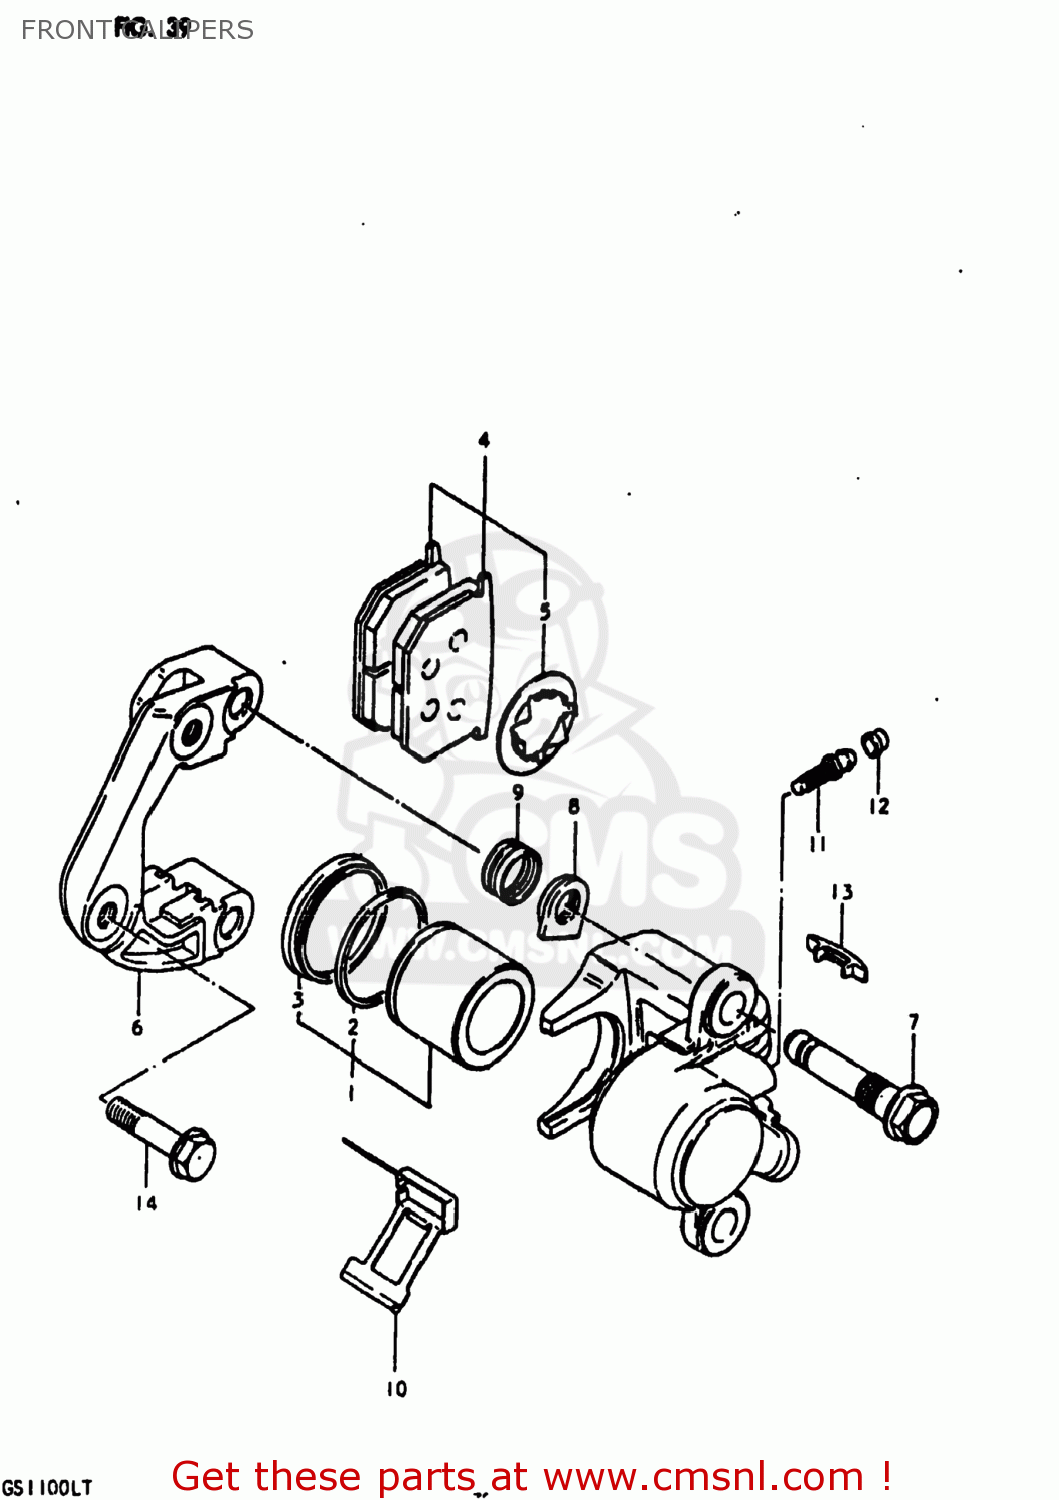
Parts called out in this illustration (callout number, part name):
0	CALIPERS ASSY.L
1	PISTON SET
2	SEAL,PISTON
3	BOOT,PISTON
4	PAD & SHIM SET (MCA)
5	SHIM,PAD
6	BRACKET
7	AXLE,CALIPER
8	NUT,CALIPER AXLE
9	BOOT
10	SPRING
11	BREATHER
12	CAP,BLEEDER PL
13	COVER,INDICATOR
14	BOLT
